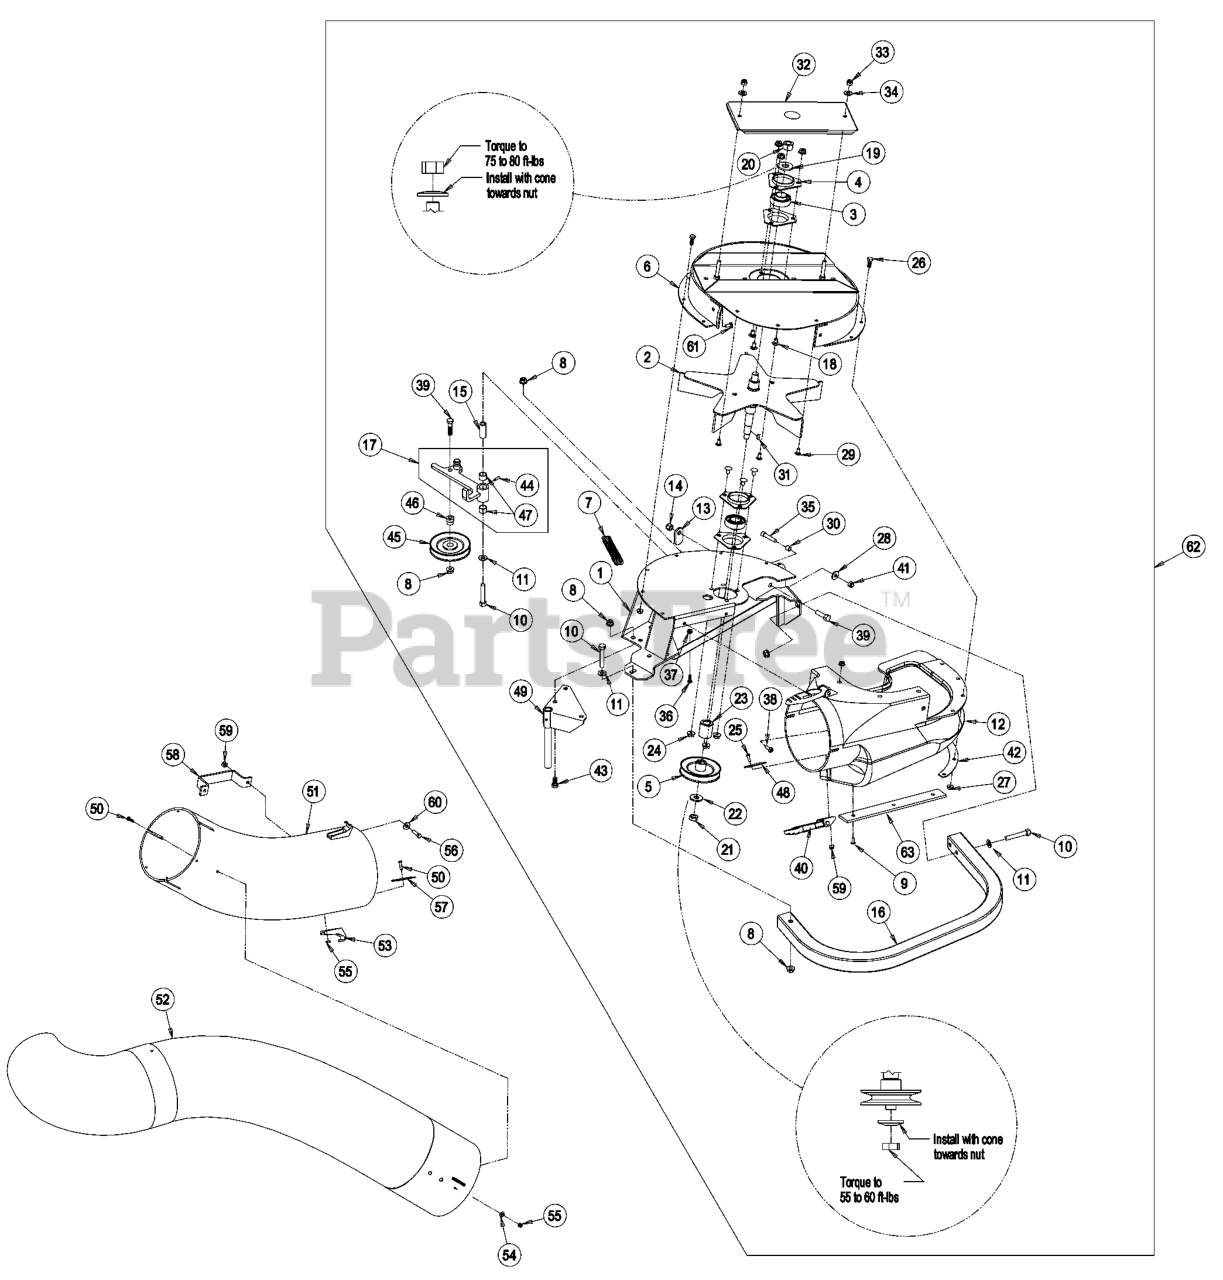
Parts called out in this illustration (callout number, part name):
1	WLD,BLOWER MOUNT
2	IMPELLER
3	BEARING
4	HOUSING-FLANGE
5	SHEAVE
6	ASM, UPPER HSG
7	SPRING-IDLER
8	NUT-HHF, WHIZ
9	RIVET-BLIND
10	SCREW-HH
11	WASHER-FLAT
12	ASM,BLOWER CHUTE LZ
13	LATCH-CATCHER, GRASS
14	NUT-LOCK, NI
15	BUSHING
17	ASM, IDLER ARM - SERVICE
18	SCREW-CARR
19	WASHER-SPRING
20	NUT-HEX
21	NUT-JAM
22	WASHER-SPRING
25	SCREW-HH
26	SCREW-HH
28	WASHER-SPRING
29	SCREW-CARR
30	BUSHING, LOCATOR
31	KEY-WOODRUFF
32	ASM, BEARING COVER
33	NUT-LOCK, NI
34	WASHER-FLAT
35	SCREW-HSH
36	SCREW-HEAD, TRUSS
39	SCREW-HH
40	LATCH-RUBBER
41	NUT-HEX
42	PLATE-BACKING, BLOWER
43	SCREW-HH
44	FITTING-GREASE
46	HUB,SPACER
47	BUSHING
48	PLATE-BACKING
49	PIN-MOUNT
50	SCREW-HWH
51	TUBE-LOWER
52	TUBE-UPPER
53	LATCH-CATCH
54	WASHER-FLAT
55	NUT-LOCK, NI
56	SCREW-HH
57	PLATE-BACKING
59	NUT-LOCK, NI
60	WASHER-FLAT
61	BOLT-CARR
62	Asm, Blower (Includes Items 1-49, 61 & Decals)
63	PLATE,REINFORCEMENT LARGE
